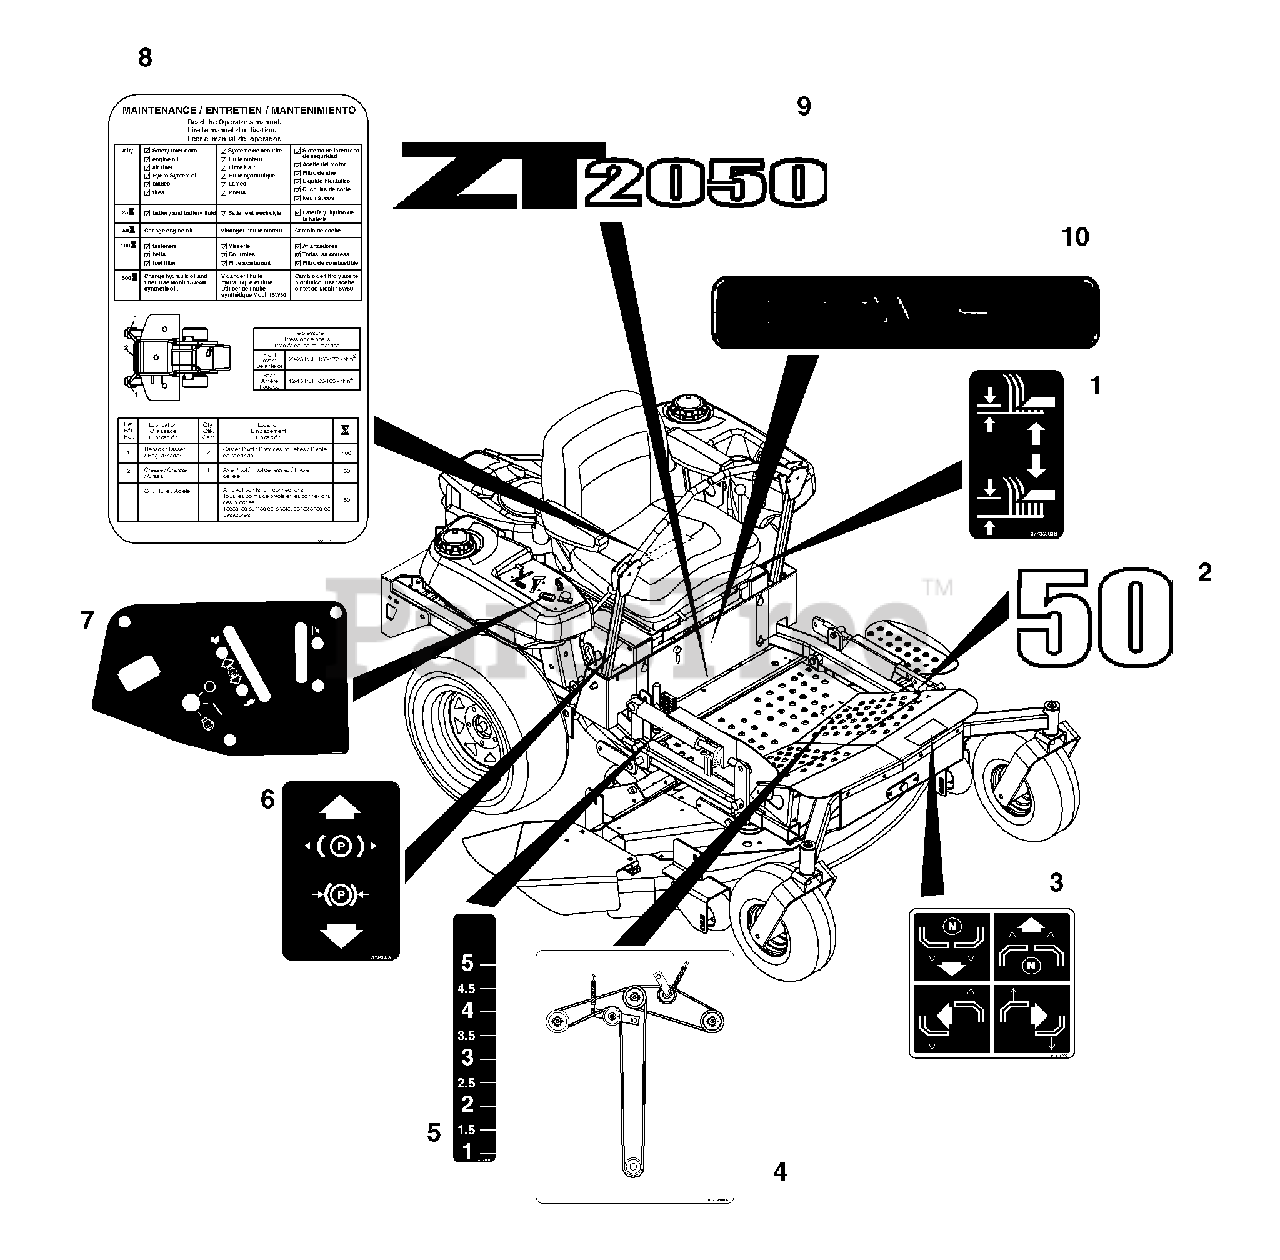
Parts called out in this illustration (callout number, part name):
1	Decal- Lift Lever
2	Decal, 50
3	Decal-Instructional-Steering
4	Decal, Belt Diagram
5	Decal, Height of Cut
6	Decal-Parking Brake Lever
7	Decal, Control Panel
8	Decal-Service Instructions
9	Decal, Gravely ZT2050 Logo
10	Decal, 15" Gravely Logo
